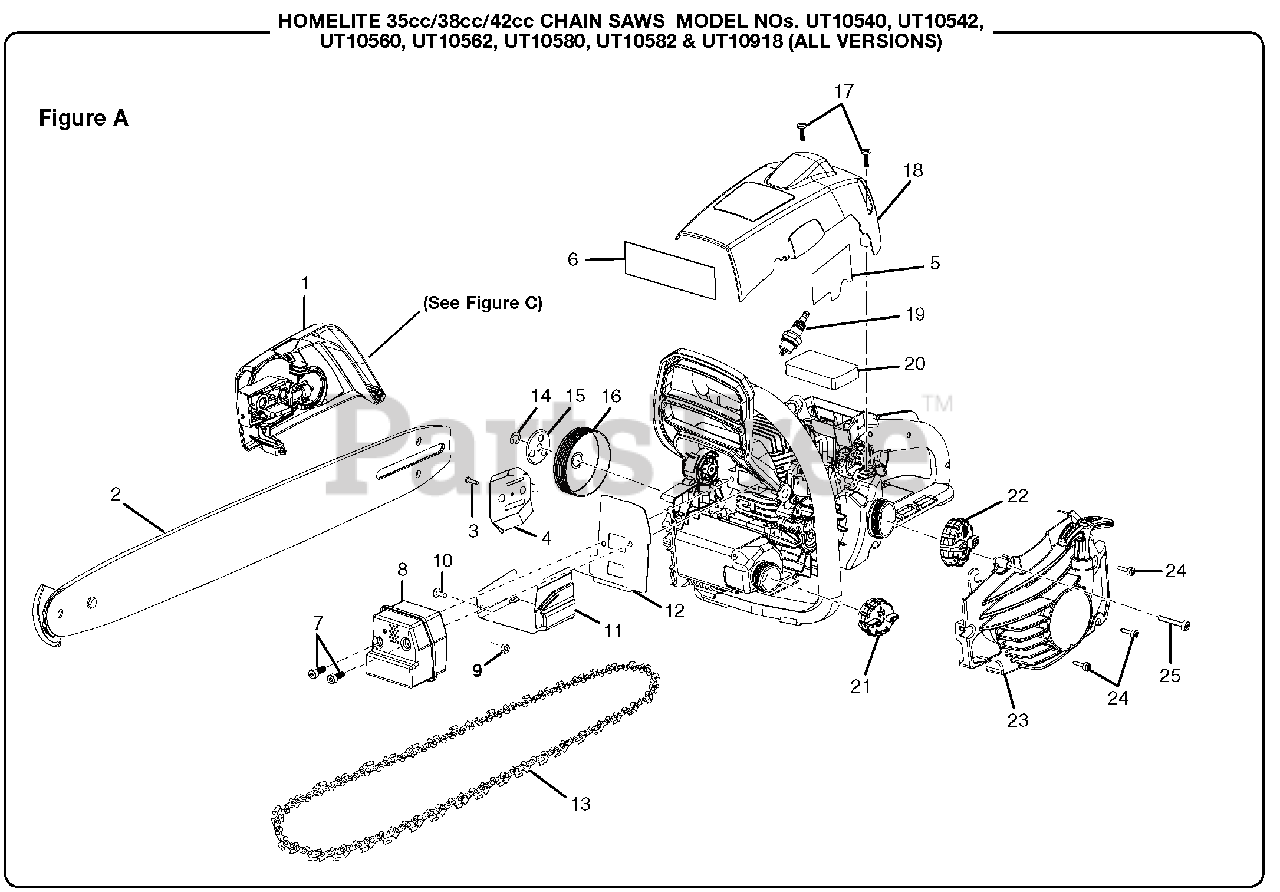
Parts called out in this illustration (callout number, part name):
1	Chain Cover Assembly
2	Guide Bar (with SAFE-T-TIP)
3	Screw (6-19 x 1/2 in.)
4	Inner Guide Plate
5	Heat Shield
6	Heat Shield
7	Screw (1/4-20 x 5/8 in.)
8	Muffler Assembly
9	Lock Nut (10-24)
10	Screw (10-24 x 5/8 in.)
11	Heat Shield
12	Muffler Gasket
13	Chain (3/8 in.): - 52 link
14	E-Clip
15	Clutch Washer
16	Sprocket Drum and Bearing Assembly (.375 chain)
17	Screw (10-16 x 16 mm)
18	Cylinder Cover
19	Spark Plug (Champion RCJ4)
20	Air Filter
21	Oil Cap Assembly
22	Fuel Cap Assembly
23	Starter Cover Assembly
24	Screw (M4 x 17 mm)
25	Screw (M4 x 22.5 mm)
